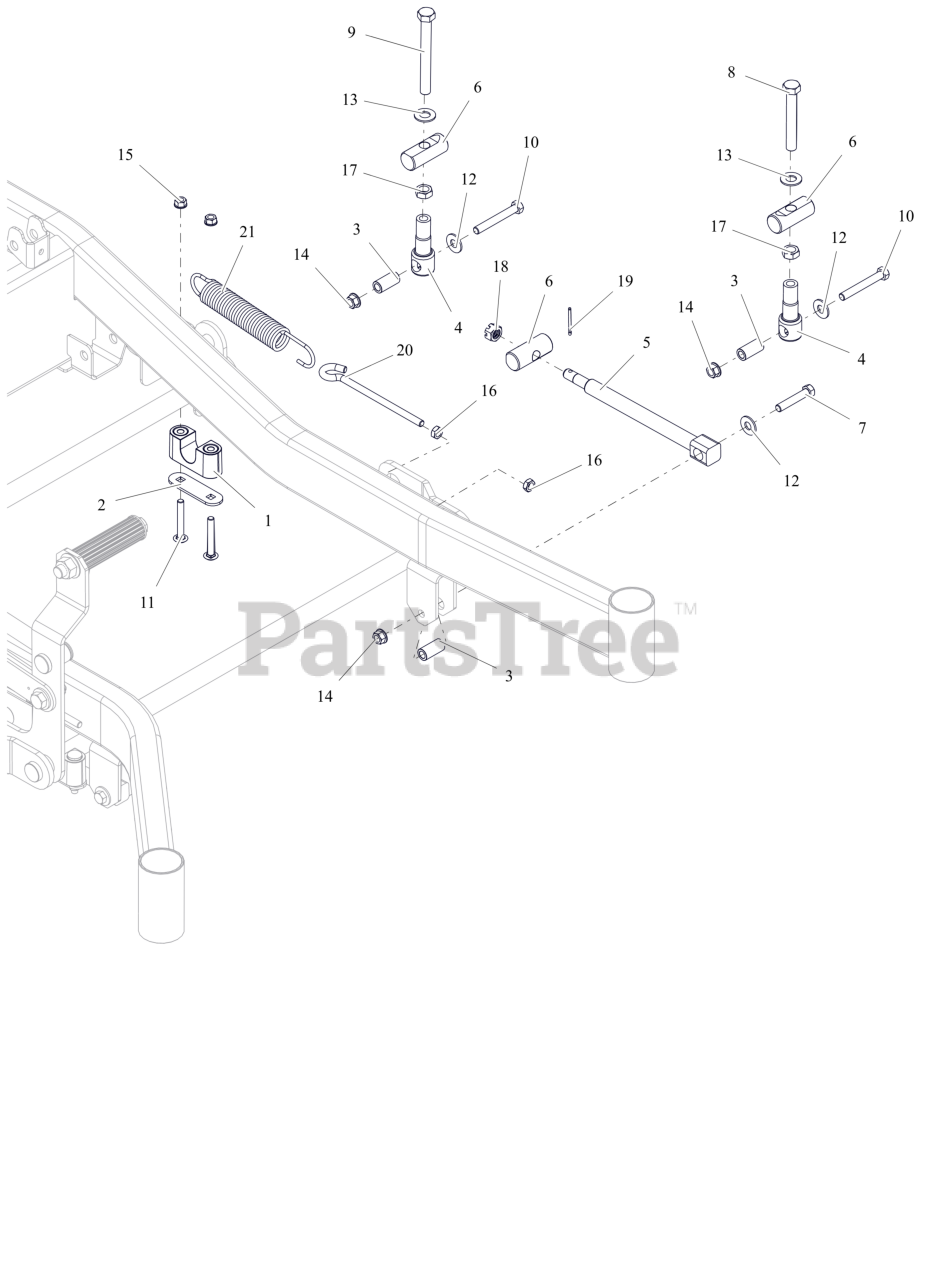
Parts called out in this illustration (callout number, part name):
1	ASM-BUSHING, DECK LIFT
2	PLATE, BEARING SUPPORT
3	SPACER, DECK LEVELING
4	LINK, DECK LIFT FORMED
5	DRAG,LINK-HD
6	PIN, DECK LIFT
7	BLT,HEX .38-16X2.00 G5 ZCC
8	BLT, HEX .50-13X3.50F G5 ZCC
9	BLT, HEX .50-13X4.50F G8 ZCC
10	BLT, HEX .38-16X2.75 G8 ZCC
11	BLT, RHSSN.31-18X2.25 G5 ZCC
12	WSHR,FLT .438X1.00X.083 ZCC
13	WSHR, FLT .557X1.040X.102 ZCC
14	NUT-LK-TOP-FLG .38-16 ZC120
15	NUT,LK-CTR-FLG .31-18 GF ZCC
16	NUT-JAM .375-16 G2 ZCC
17	NUT-JAM .500-13 G2 ZCC
18	NUT-SL .50-13
19	PIN,CTR.12X1.25EXTPRSQCT ZC120
20	BOLT,.38-16 X 5.25-.62 DIA EYE
21	SG-TENS .162X1.25X8.25 WLD 25
